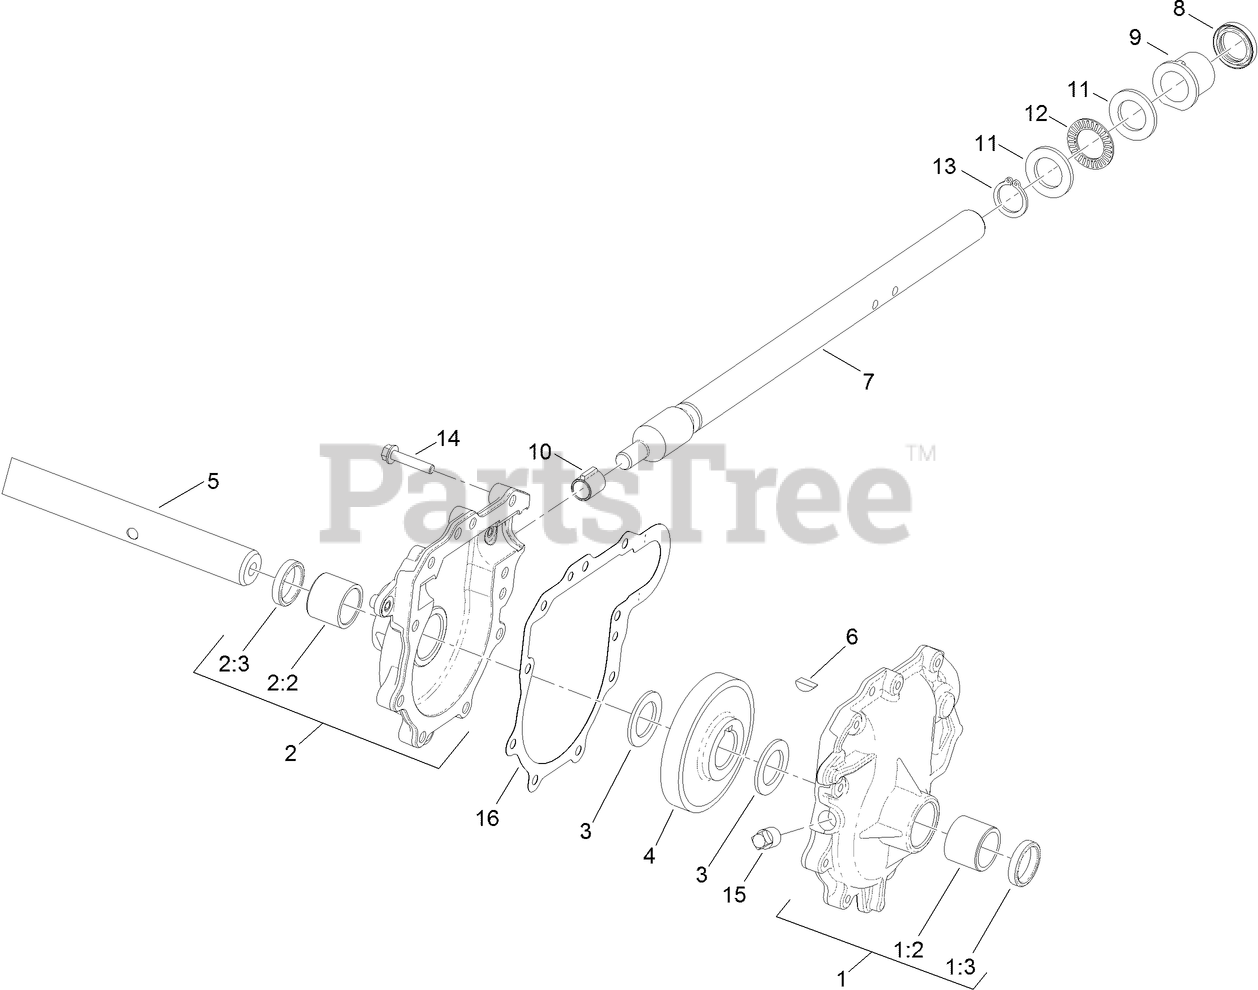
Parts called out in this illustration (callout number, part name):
1	LH AUGER GEARCASE ASM
1:2	BUSHING-SLEEVE
1:3	SEAL-OIL
2	RH AUGER GEARCASE ASM
2:2	BUSHING-SLEEVE
2:3	SEAL-OIL
3	WASHER-THRUST
4	GEAR-HELICAL
5	SHAFT-AUGER
6	KEY-WOODRUFF
7	SHAFT-IMPELLER
8	SEAL-OIL
9	BUSHING-INPUT
10	BUSHING-WORM
11	WASHER-THRUST
12	BEARING-THRUST
13	RING-RETAINING, EXT
14	SCREW-HWHTF
15	PLUG-PIPE, SQH
16	GASKET-GEARCASE, AUGER
